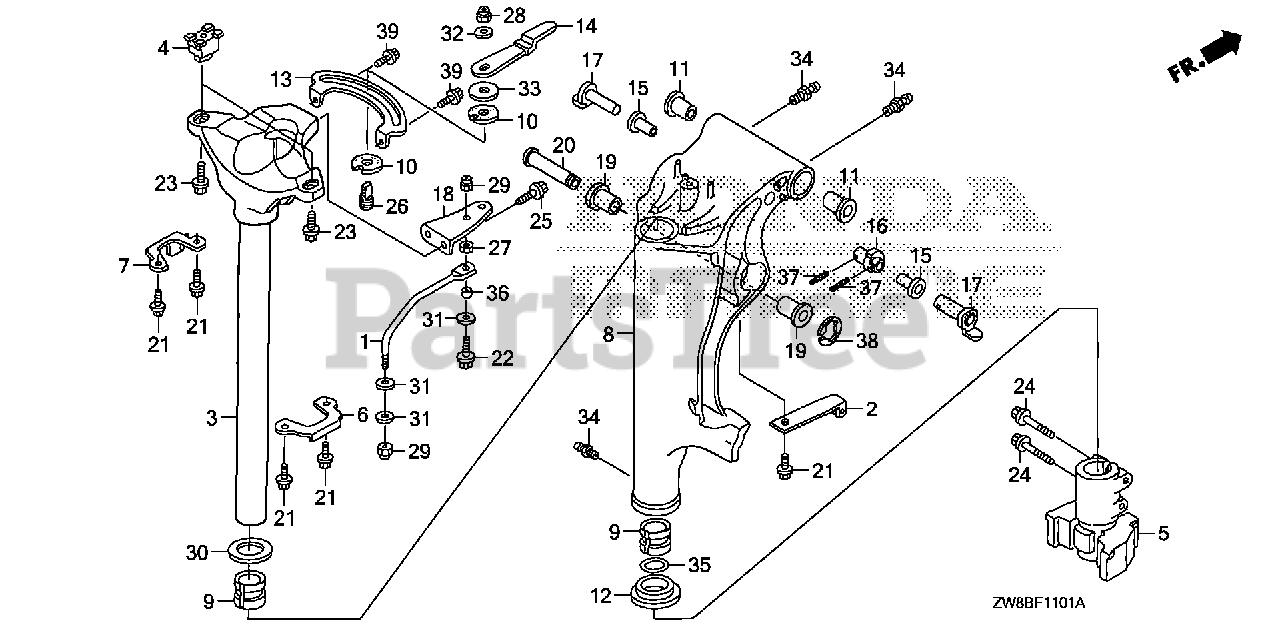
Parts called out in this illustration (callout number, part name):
2	SPRING, CLICK
3	FRAME, MOUNTING (L)
4	RUBBER, MOUNTING (UPPER)
5	RUBBER, MOUNTING (LOWER)
6	COVER, MOUNTING RUBBER (UPPER)
7	COVER, MOUNTING RUBBER (UPPER) (PT)
8	CASE, SWIVEL *NH282MU* (L)(PT) (OYSTER SILVER METALLIC-U)
9	LINER, SWIVEL CASE
10	BLOCK, FRICTION
11	BUSH, SWIVEL CASE
12	COLLAR, SWIVEL CASE
13	PLATE, FRICTION
14	LEVER, FRICTION
15	BUSH, TILT ARM
16	BRACKET, TILTING
17	STOPPER, TILT
19	BUSH, CYLINDER (LOWER)
20	PIN, CYLINDER (UPPER)
21	BOLT, FLANGE (6X12)
23	BOLT, FLANGE (10X25)
24	BOLT, FLANGE (8X45)
26	BOLT, STUD (8X26)
28	NUT, SELF-LOCK (8MM)
30	WASHER, THRUST
32	WASHER (8MM)
33	WASHER, NYLON (8MM)
34	NIPPLE, GREASE
35	O-RING (34X2.4)
37	PIN, SPRING (2.5X20)
38	E-RING (15MM)
39	BOLT, FLANGE (6X12)
